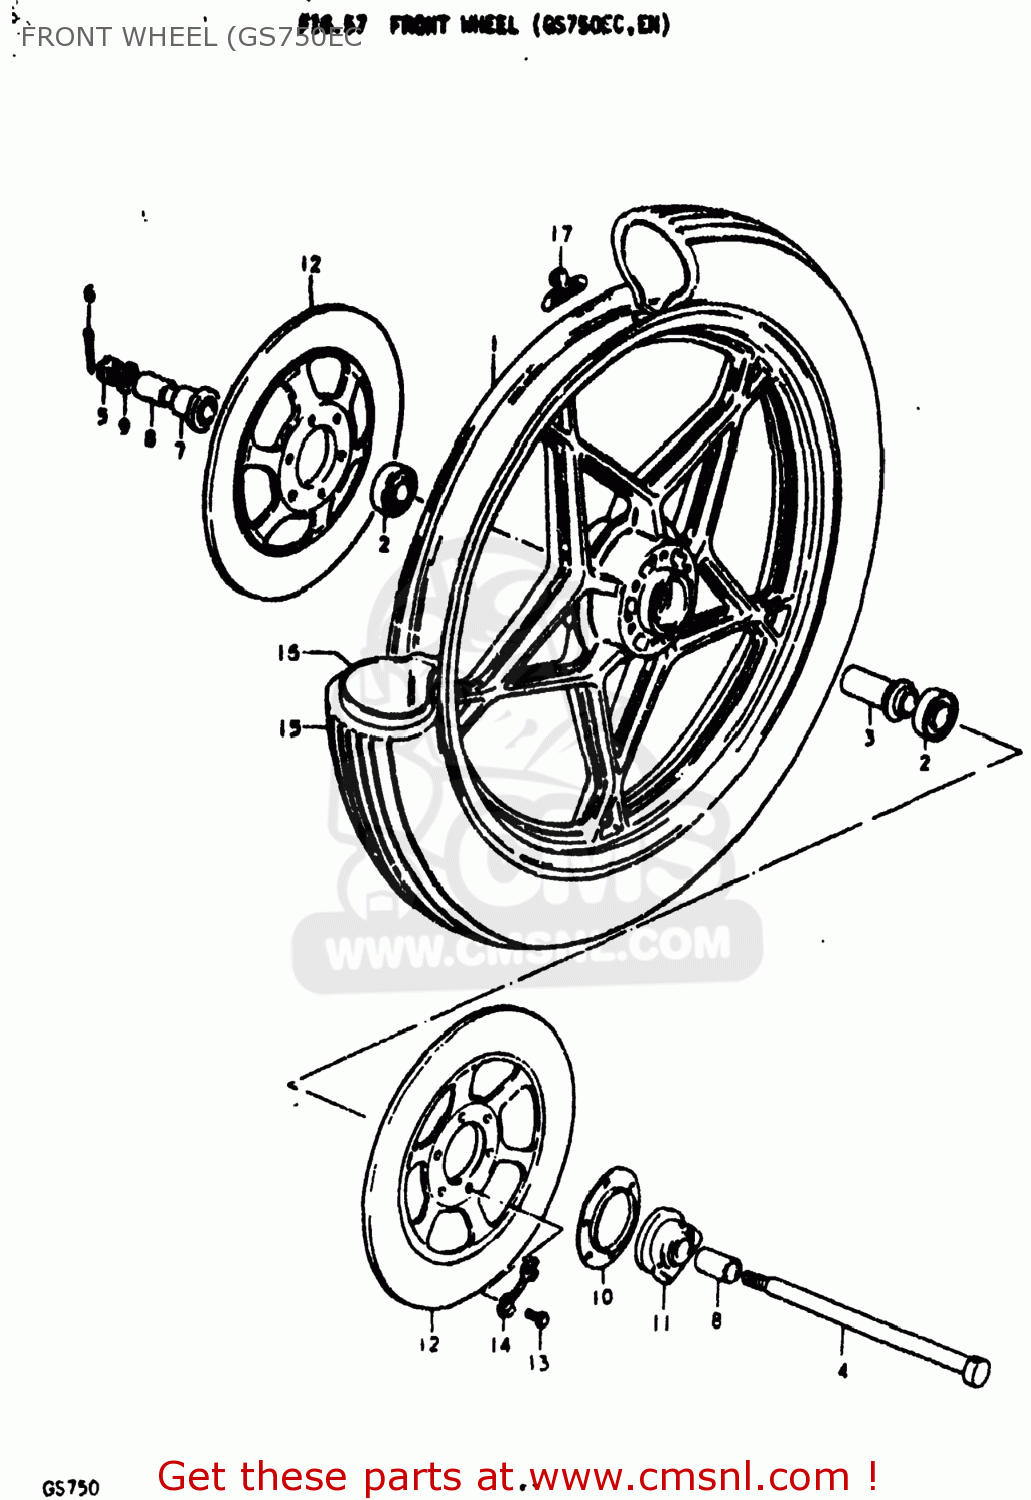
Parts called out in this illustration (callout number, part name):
1	WHEEL, FRONT
2	BEARING
3	SPACER,FR HUB BEARING
4	AXLE,FRONT
5	NUT 12MM
6	COTTER PIN
7	SPACER,FR AXLE,R
8	SPACER(15X22X30)
9	WASHER
10	DUST SEAL,SPEEDOMETER GEAR BOX
11	BOX ASSEMBLY,SPEEDOMETER GEAR
12	DISC,REAR BRAKE
13	BOLT(8X25)
14	WASHER
15	TIRE,FRONT
16	TUBE,INNER
17	BALANCER,WHEEL
